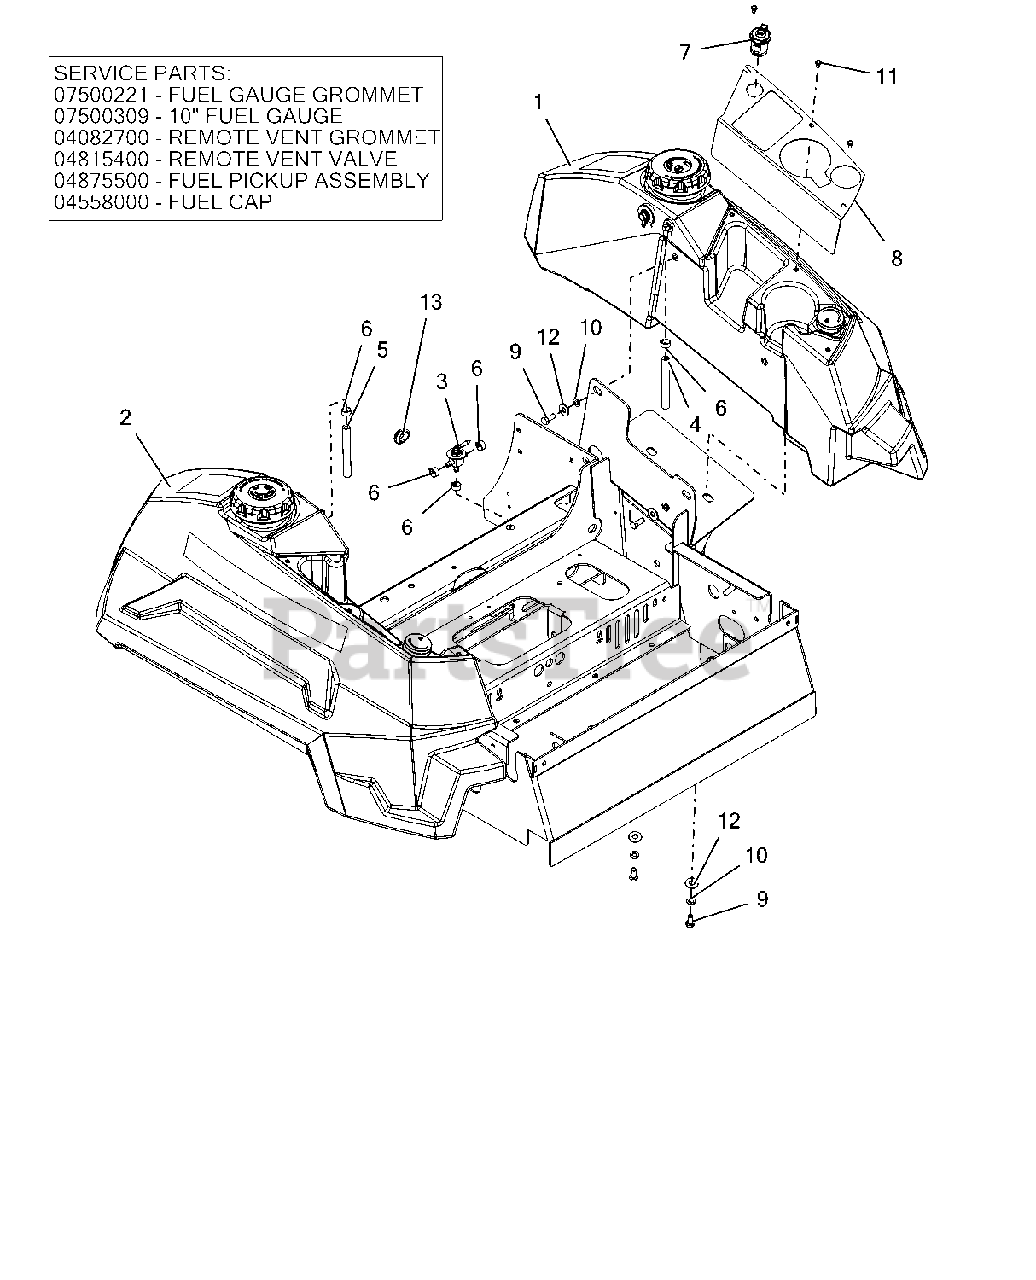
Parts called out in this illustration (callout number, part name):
1	ASM, LH FUEL TANK
2	ASSY-RH, PT400 FUEL TANK
3	VALVE - FUEL
4	HOSE, .25 LOW-PERM BULK GAS
5	HOSE, .25 LOW-PERM BULK GAS
6	CLAMP, FUEL LINE
7	PORT, 12 VOLT POWER
8	CUP HOLDER/POCKET PLATE - RED
9	@BLT-HEX .31-18X.75 GR5 YWZC
10	@WSHR-LK .31X.078 REG YWZC
11	SCR-MCH 10-24X.38 HWHSTAINLESS
12	WSHR-FL-STL.38X.875X.083 YWZC
13	GROMMET,RUBBER 5/8 ID/1.13 OD
14	GROMMET, FUEL GAUGE
15	GAUGE, REMOTE FUEL SEALED 10"
16	GROMMET, REMOTE VENT NITRILE
17	VALVE, 2-WAY
18	ASSM,LRG TANK FUEL PICKUP LINE
19	CAP, FUEL VENTIN AUTOLOCK
